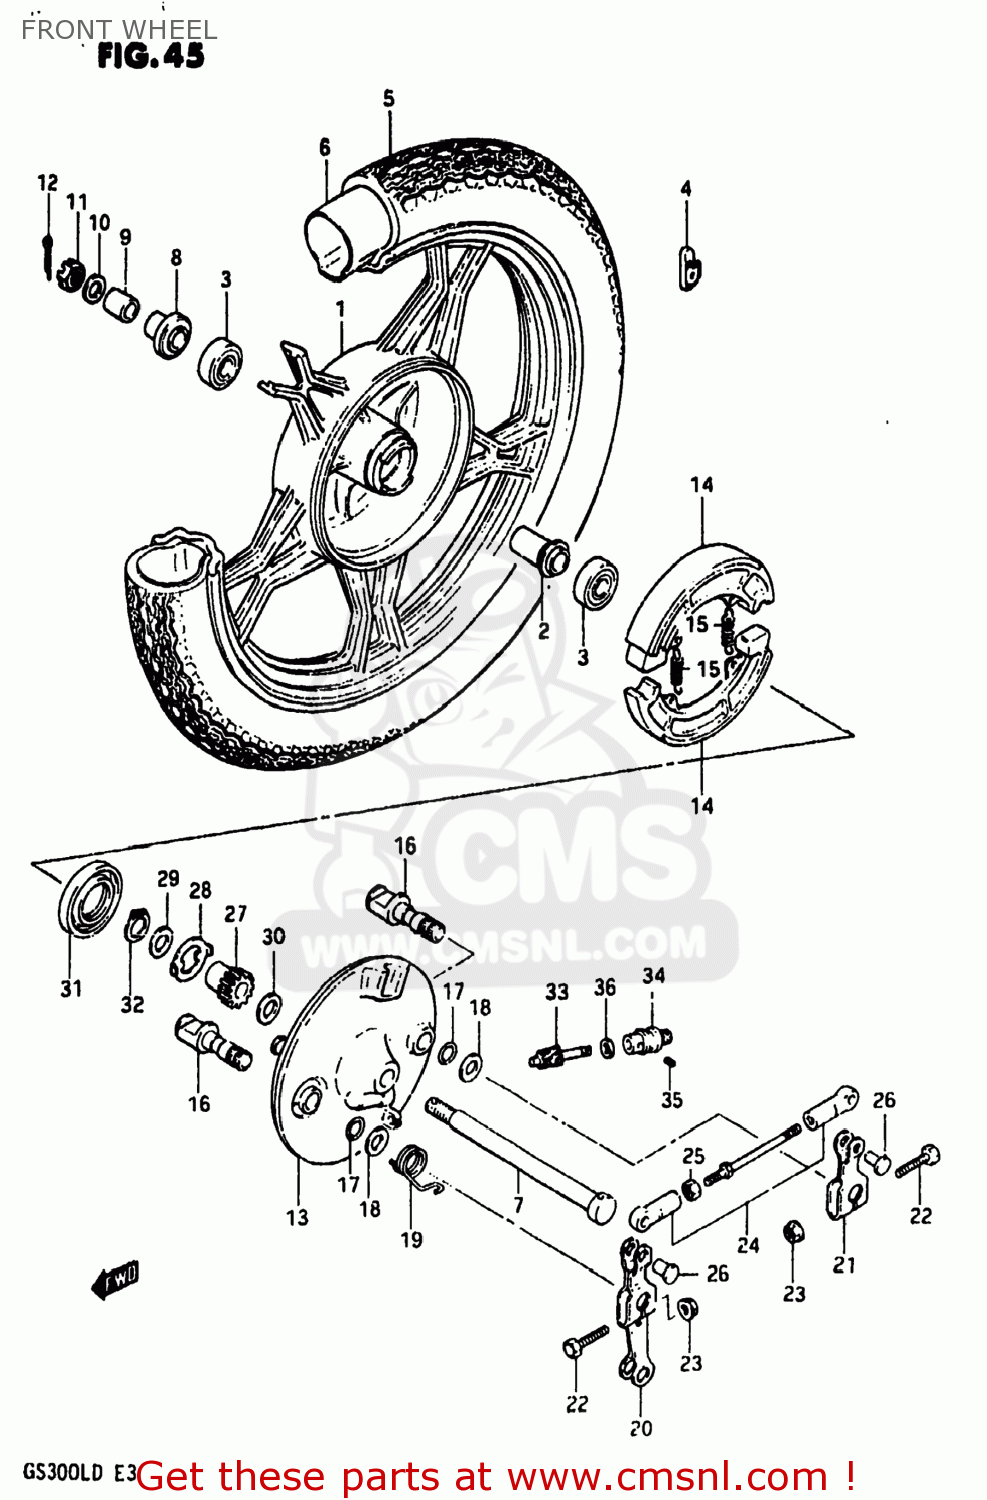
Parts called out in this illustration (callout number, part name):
1	CASTING WHEEL,FRONT 1.85
2	SPACER,FRONT HUB BEARING
3	BEARING
4	BALANCER,WHEEL
5	TIRE
6	TUBE,INNER
7	AXLE,FRONT
8	SPACER,FR AXLE,R
9	SPACER(15X22X30)
10	WASHER
11	NUT 12MM
12	COTTER PIN
13	PANEL,FRONT HUB
14	SHOE,BRAKE
15	SPRING
16	CAM,FRONT BRAKE
17	O-RING,BOSS
18	WASHER (15X24X1.6)
19	SPRING
20	LEVER,FRONT BRAKE CAM NO
21	LEVER,FRONT BRAKE CAM NO
22	BOLT
23	NUT
24	SHOE SET,BRAKE
25	NUT
27	GEAR,SPEEDOMETER
28	DRIVER,SPEEDOMETER GEAR
29	WASHER(22.5X27X1)
30	SHIM
31	OIL SEAL
32	CIRCLIP
33	PINION,SPEEDOMETER
34	BUSH,METER GEAR OUTER
35	SCREW
36	WASHER (5.1X9X0.4)
